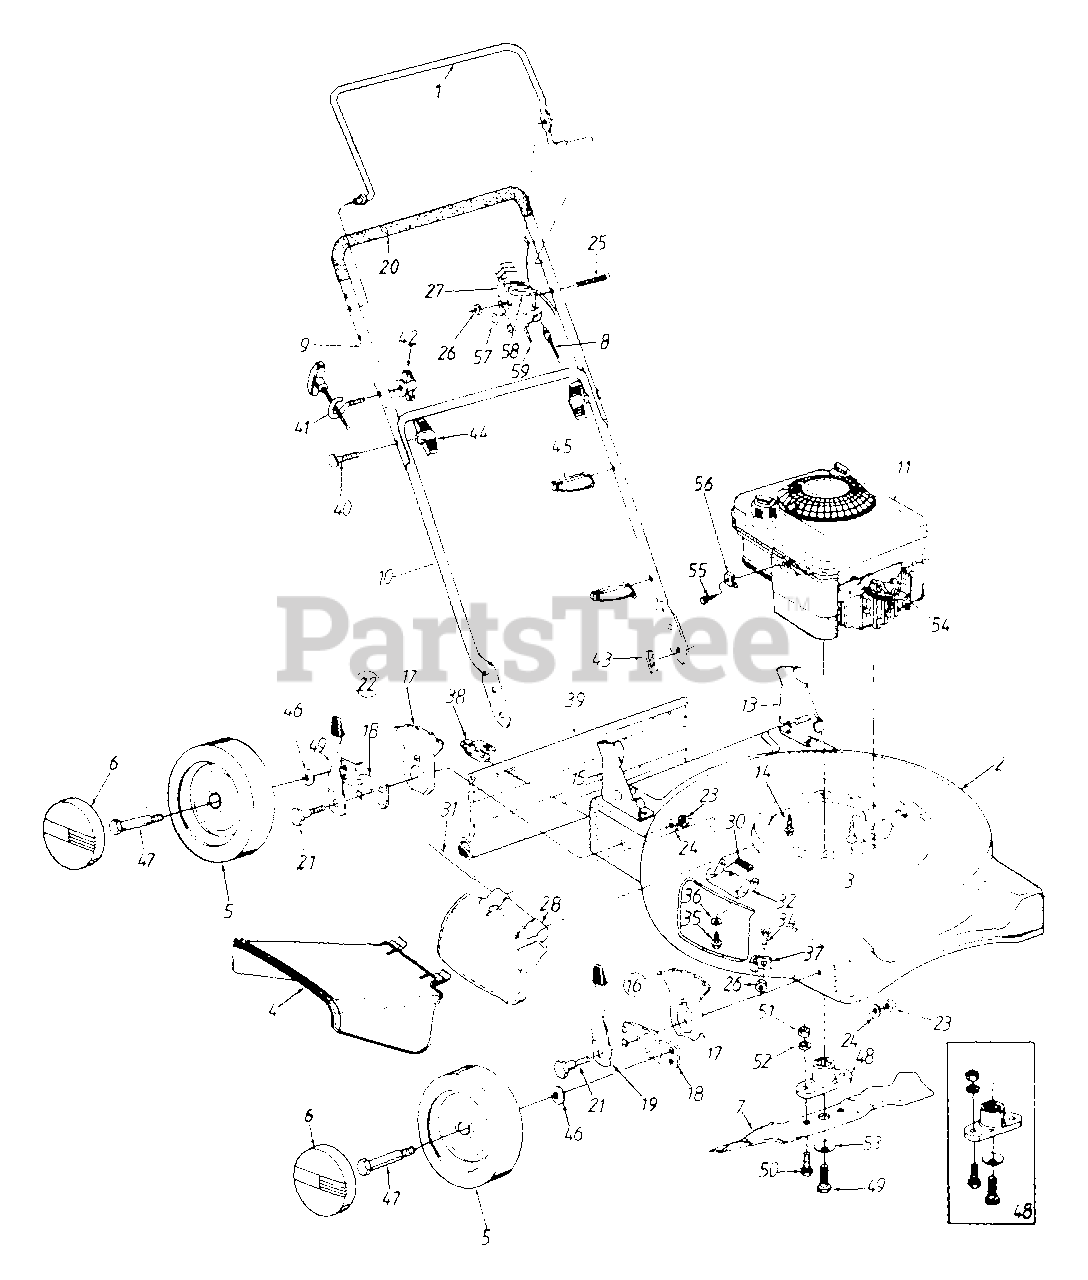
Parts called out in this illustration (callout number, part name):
2	20" Deck Assembly
3	Hex TT-Tap Scr. 3/8-16 x 1" Lg.
4	Side Chute Deflector
5	Wheel Ass'y.
6	Hub Cap
7	20" Mulching Blade
8	Control Cable - 39" (Green)
11	Engine
17	Height Adj. Plate
19	Spring Lever Ass'y. w/Knob
20	Foam Grip
21	Shoulder Bolt .5" Dia. x .434"
22	Height Adj. Ass'y.- L.H.
23	Hex Nut 3/8-16 Thd.
24	Bell-Wash ..39" I.D.
25	Oval C-Sunk Mach. Scr.
26	Hex L-Nut 1/4-20 Thd.
27	Throttle Body
28	Mulching Plug Ass'y.
30	Torsion Spring
31	Hinge Pin
34	Carriage Bolt 1/4-20 x .5" Lg.
35	Hex TT-Tap Scr. 1/4-20 x .5" Lg.
36	Bell-Wash..265" I.D.
39	Rear Flap
40	Carriage Bolt 5/16-18 x 2" Lg.
41	Rope Guide
42	Wing Nut 1/4-20 Thd.
43	Int. Cotter Pin 5/16" Dia.
44	Handle Knob
45	Cable Tie
46	Bell-Wash .38" I.D. x .88" O.D.
47	Axle Bolt
48	Blade Adapter Kit
49	Hex Bolt 3/8-24 x 1.5" Lg.- Gr. 5
50	Hex Bolt 3/8-24 x 1" Lg.
51	Hex Nut 3/8-24 Thd.
52	L-Wash. 3/8" I.D.
53	Bell-Wash .39" I.D.
54	Spark Plug Boot
55	Hex Self-Tap Scr. #10-32 x .62" Lg.
56	Cable Clamp
57	Spr. Wash..66" I.D.
58	Throttle Lever
59	Throttle Wire - 51" (Red)
